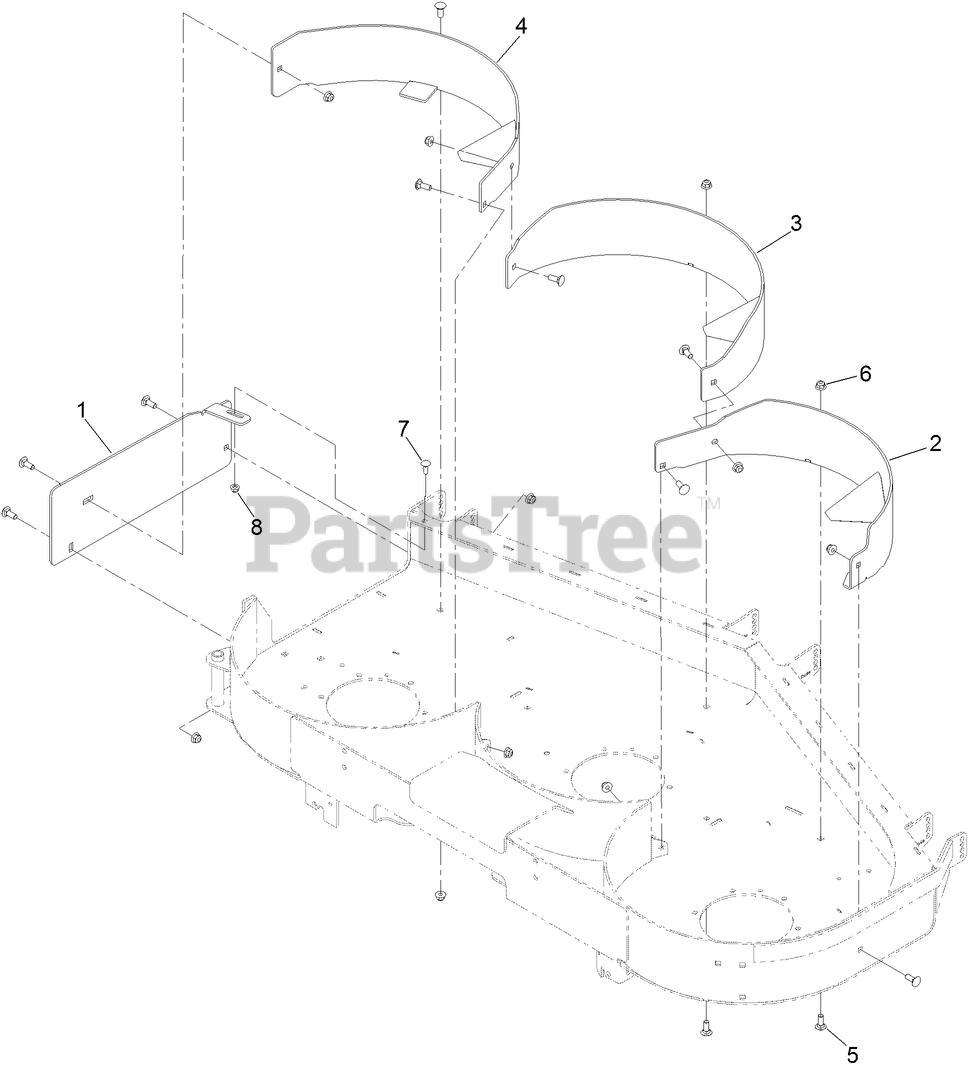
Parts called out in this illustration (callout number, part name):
1	PLATE-COVER, DISCHARGE
2	BAFFLE-RECYCLER, LH
3	BAFFLE-CENTER
4	BAFFLE-RH
5	BOLT-CARR
6	NUT-HF, NI
7	SCREW-CARR
8	NUT-HF, NI
